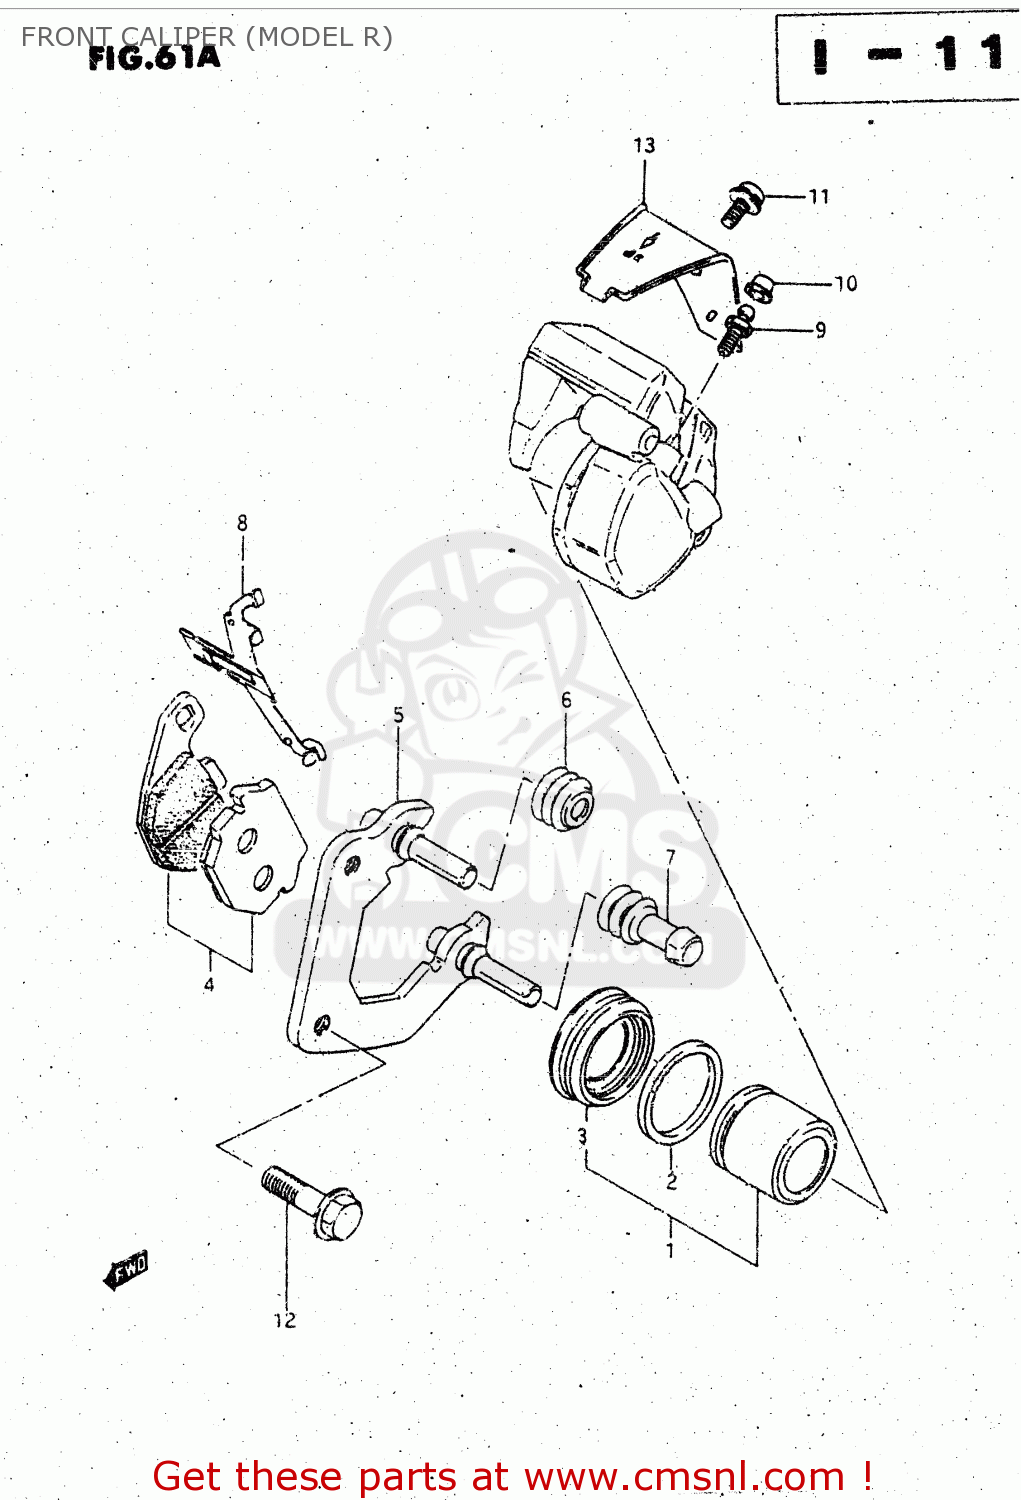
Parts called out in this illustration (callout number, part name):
1	PISTON SET
2	SEAL,PISTON
3	BOOT,PISTON
4	PAD SET (NAS)
5	CARRIER,L
6	BOOT,AXLE
7	INSULATOR,AXLE
8	SPRING,PAD
9	BLEEDER
10	CAP,BREATHER
11	SCREW
12	BOLT
13	PROTECTOR,CALIPER
